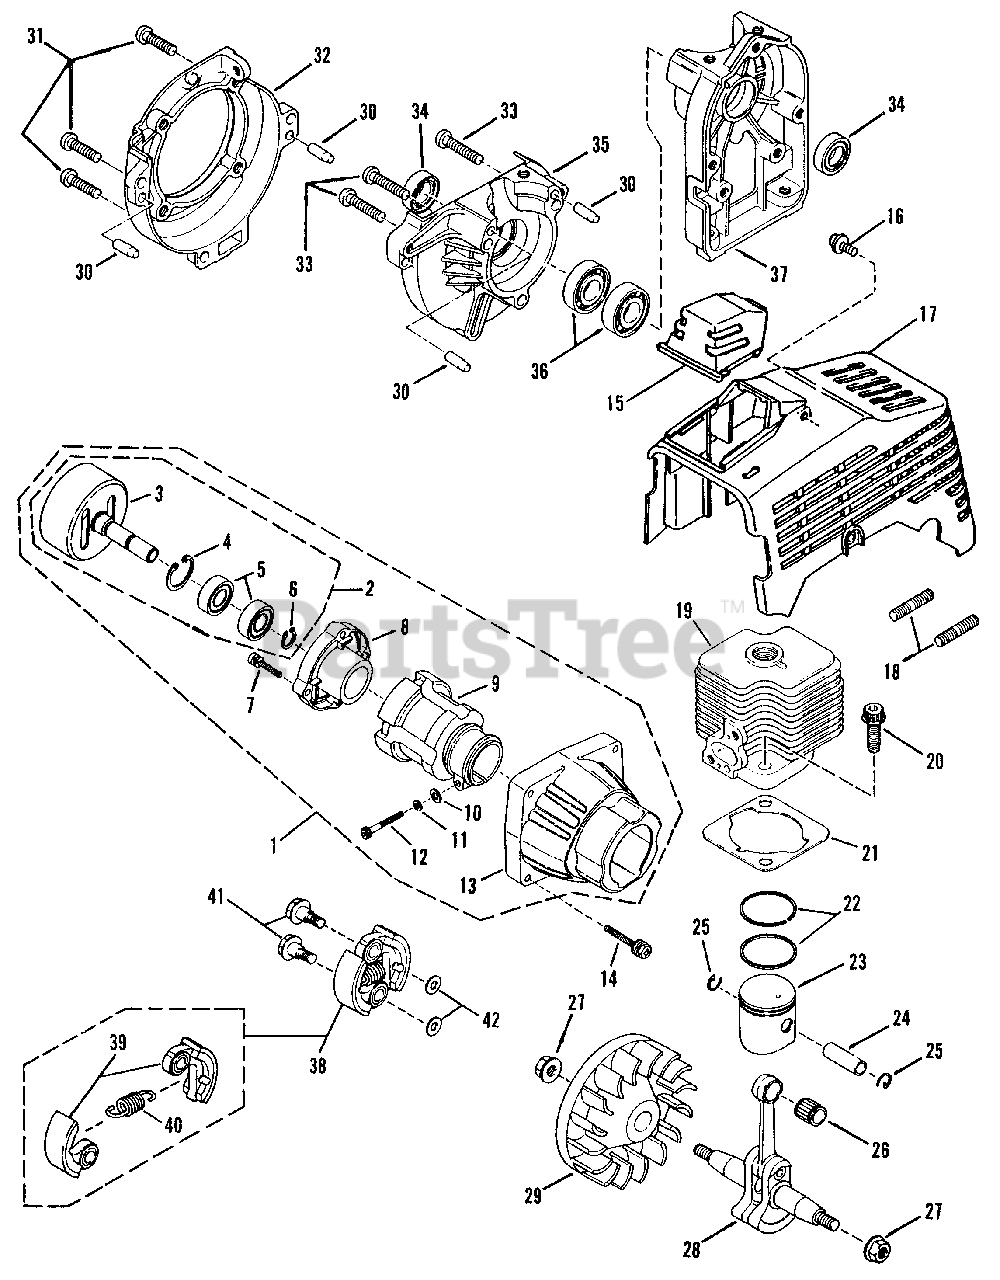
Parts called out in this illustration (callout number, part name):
1	ASSEMBLY, Clutch Case
2	ASSEMBLY, Clutch Drum
3	DRUM, Clutch 5.1MM Square Hole, 21x12MM Shank
4	RING, C-Snap 28mm
5	BEARING, M12-Ball
6	RING, C-Snap 12mm
7	SCREW, M5x20mm
8	COVER, Clutch Bearing
9	RING, Insert
10	WASHER, Flat M5
11	WASHER, Lock M5
12	SCREW, M5x25mm Socket
13	CASE, Clutch
14	BOLT, M6x28mm Hex Head
15	GUARD, Spark Plug
16	SCREW, M5x12mm
17	COVER, Cylinder
18	BOLT, Stud
19	CYLINDER
20	BOLT, Flange
21	GASKET, Cylinder
22	RING, Piston
23	PISTON
24	PIN, Piston
25	CLIP, Piston Pin
26	BEARING, Needle
27	NUT, Conical
28	CRANKSHAFT ASSEMBLY
29	FLYWHEEL
30	PIN, Dowel
31	BOLT/WASHER
32	CASE, Fan
33	SCREW, M5x25mm
34	SEAL, Oil
35	CASE, Drive
36	BEARING, Ball
37	CASE, Starter
38	CLUTCH ASSM'Y.
39	SHOE, Clutch
41	BOLT, Clutch
